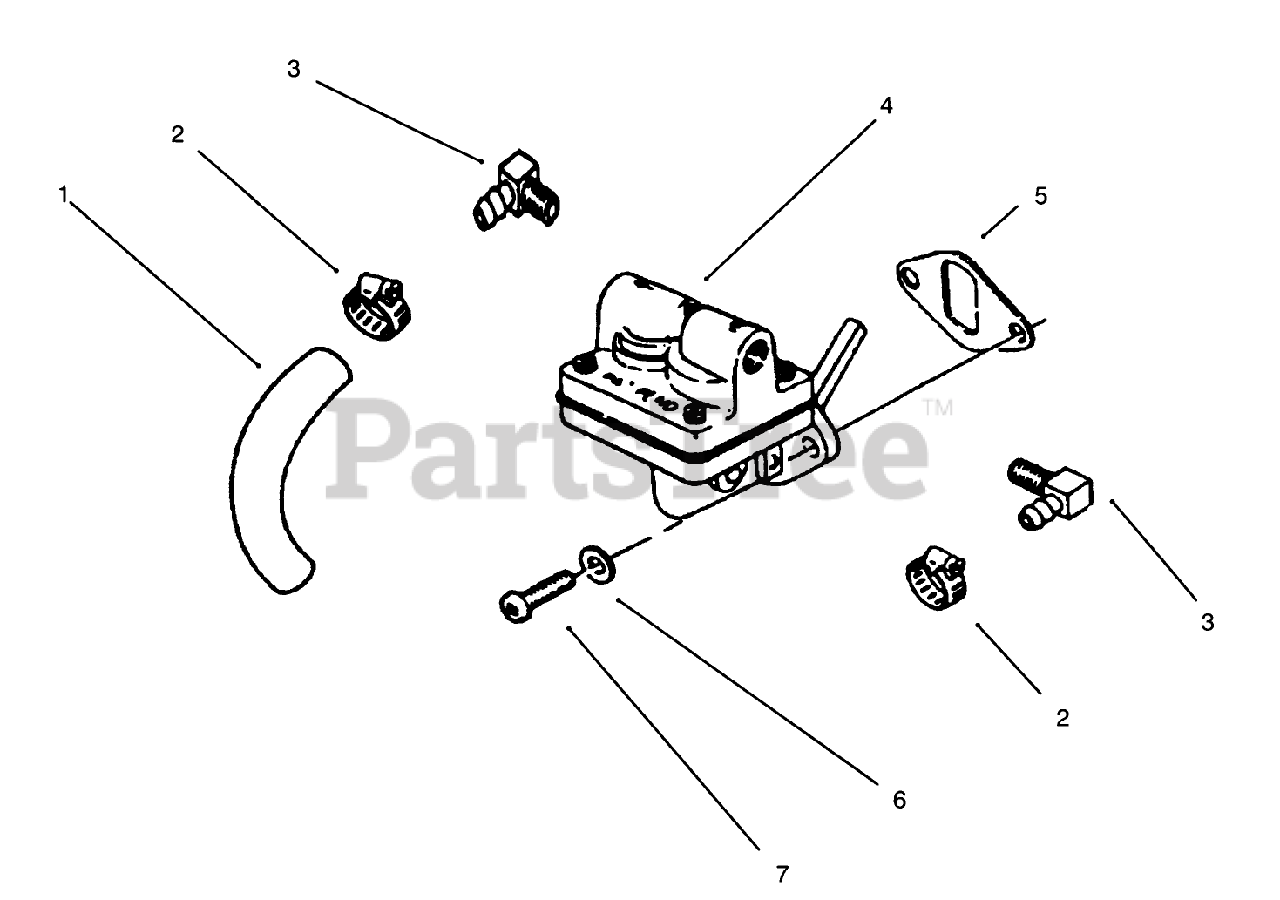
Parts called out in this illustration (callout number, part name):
1	KOHLER 25-353-01
2	KOHLER X-426-9
3	KOHLER 25-155-02
4	KOHLER 47-559-08
5	KOHLER 25-041-05
6	KOHLER X-25-63
7	KOHLER X-174-2
